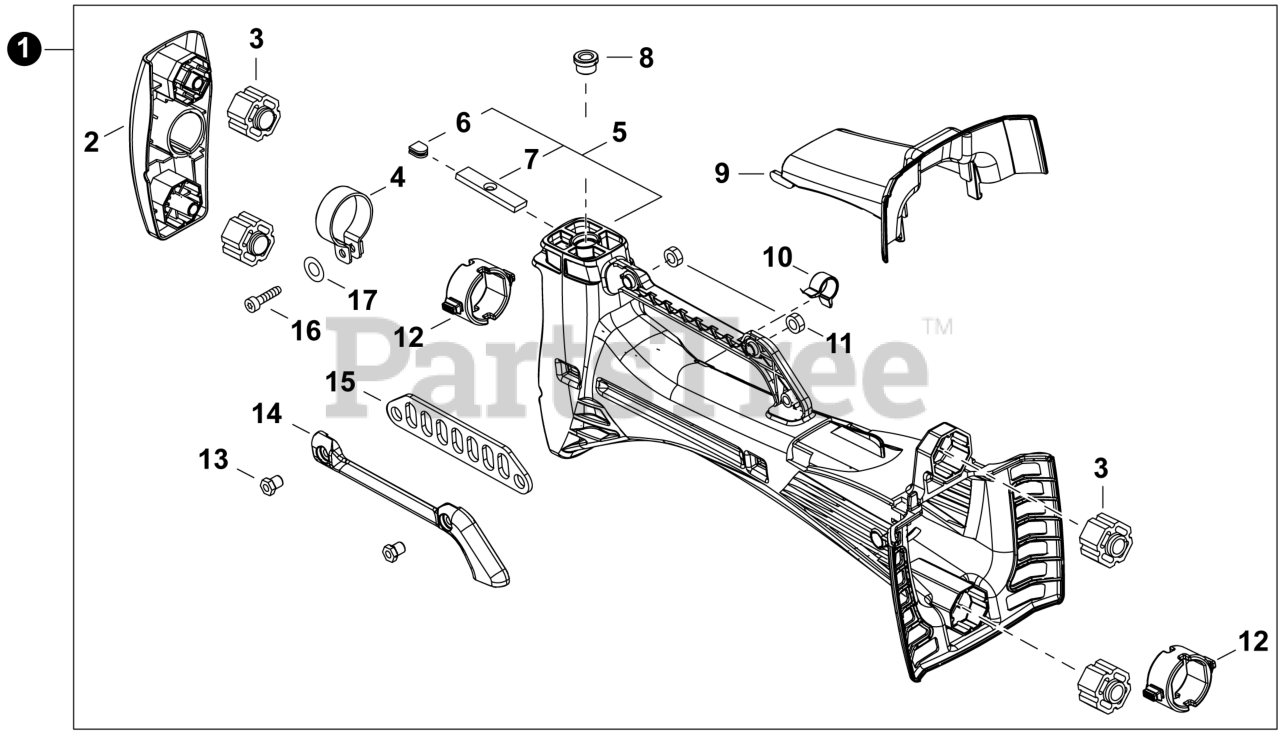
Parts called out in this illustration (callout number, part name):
1	HANDLE ASSY - SUPPORT
2	BRACKET, CUSHION
3	CUSHION
5	SUPPORT ASSY, HANDLE
6	GROMMET, PLUG
7	NUT - 8
8	COLLAR 8
9	GUIDE, CABLE
12	STOPPER, HANDLE
13	BOLT, TORX 5x16
15	PLATE, EYE
16	BOLT, TORX 6x20
17	WASHER 6.5x13x1
